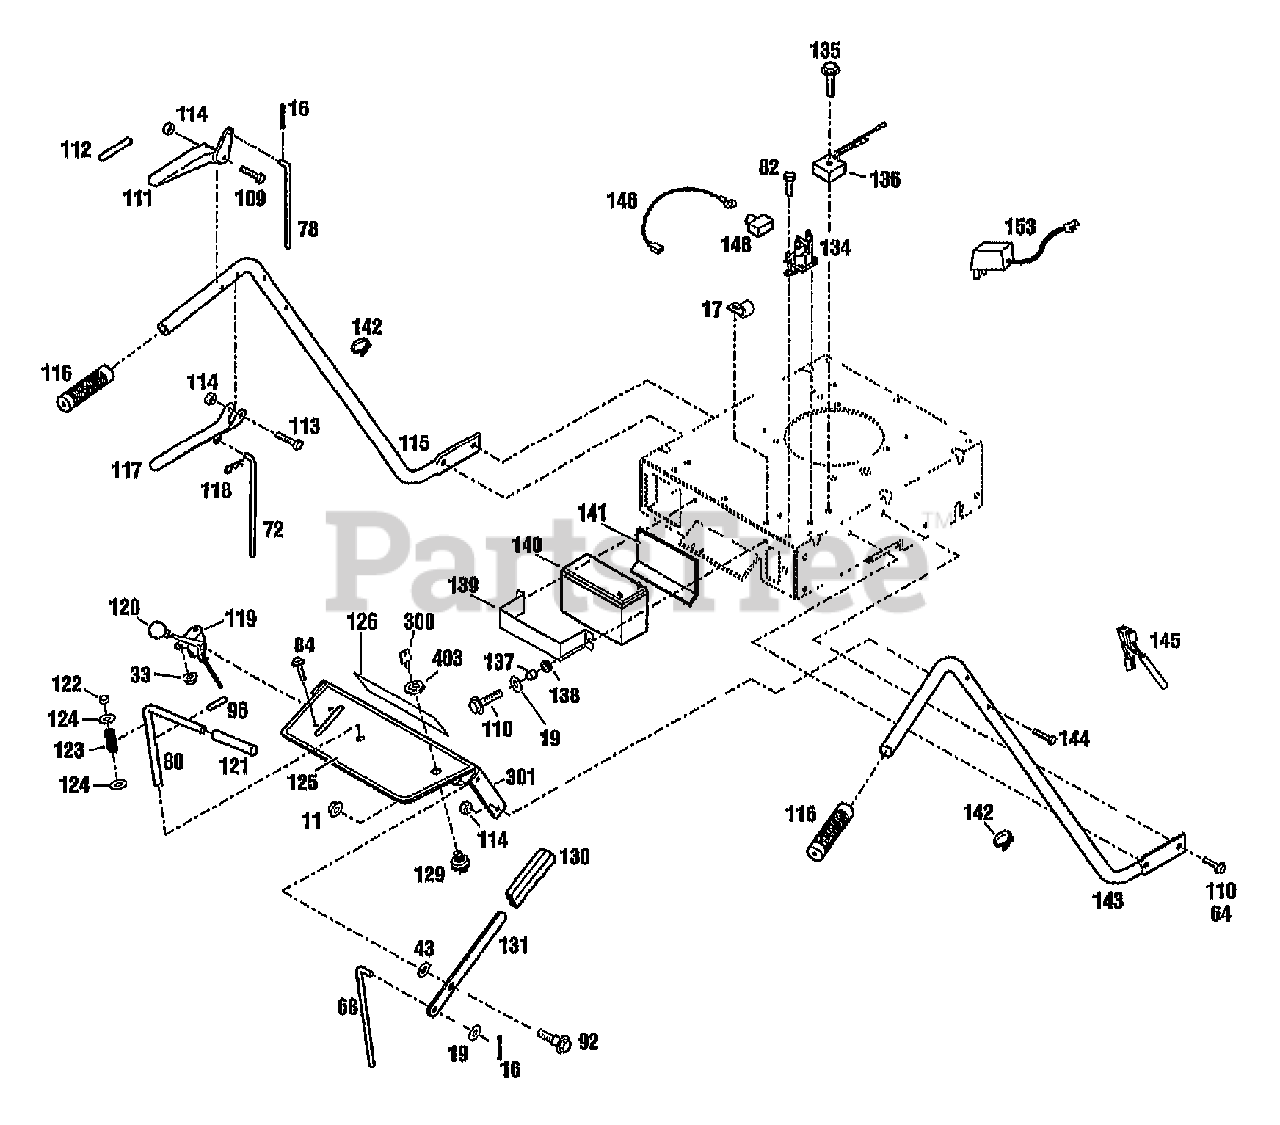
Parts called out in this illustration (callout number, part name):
11	NUT-HFLK 3/8-16 ZP
16	PIN-COTTER .093X.625
17	CLIP-CLAMP .25 ID
19	WASHER-FLAT 5/16 SAE
33	NUT-HF/LK 1/4-20 ZP
43	WASHER-FLAT 1.0X.516X.031
64	NUT-HFLK 5/16-18 ZP
68	ROD-UPPER BLADE
72	ROD-UPR TRANSMISSION
78	ROD-UPPER BRAKE
80	LEVER-SHIFT
82	SCR 1/4-20X.5 FL SELF TAP {34067,34069}
84	SCR-HFLK 1/4-20X.50 ZP
92	BOLT-SHOULDER MOWER
96	PIN-ROLL .25X2.25
109	SCR-HH 1/4-20X1.75 G5 ZP
110	SCR-HFLK 5/16-18X.75 ZP
111	LEVER-CONTROL
112	DECAL-OPC MOWERS
113	SCR-HH 1/4-20X1.5 G5ZP
114	NUT-HT LK 1/4-20
115	HANDLEBAR-LH
116	GRIP-FLEX
117	HANDLE-CONTROL MOWER
118	PIN-CLIP .08
119	CABLE-THROTTLE CONTROL {34068,34069}
119	CONTROL-THROTTLE {34067,34066}
120	KNOB
121	GRIP-HANDLE
122	BUSHING-.5X.21 NYLON FLNG
123	SPRING-COMPRESSION
124	WASHER-1.06X.531X.1 ZP
125	DECAL-WARNING {34067}
125	DECAL-WARNING {34068}
125	DECAL-WARNING {34069}
125	DECAL-WARNING {34066}
126	DECAL-T/B HIGH WHEEL
129	ASSM-KEYSWITCH {34069}
129	SWITCH-IGNITION 5.5HP {34067}
130	GRIP-HANDLE
131	LEVER-MOWER ENGAGE ZP
134	SOLENOID {34069}
135	SCR-HFLK {34069}
136	REGULATOR {34069}
137	SPACER {34069,34067}
138	GROMMET {34069,34067}
139	BRACKET-BATTERY {34069,34067}
140	BATTERY {34069,34067}
141	PAD-BATTERY {34069,34067}
142	TIE-CABLE NYLON BLACK
143	HANDLEBAR-RH
144	SCR-HH 1/4-20X1.75 G5 ZP
145	HARNESS-WIRING {34069}
146	ASSM-WIRE LEAD {34069}
148	BOOT-CABLE {34069}
153	CHARGER-BATTERY {34069,34067}
300	KEY-IGNITION {34068}
301	ASSM-CONSOLE {34067}(INCL. 125)
301	ASSM-CONSOLE 26" 3 SPD {34068}(INCL. 125)
301	ASSM-CONSOLE 26" EL 3 SPD {34069}(INCL. 125)
301	ASSM-CONSOLE 22" 3 SPD {34066}(INCL. 125)
403	NUT-IGNITION SWITCH
